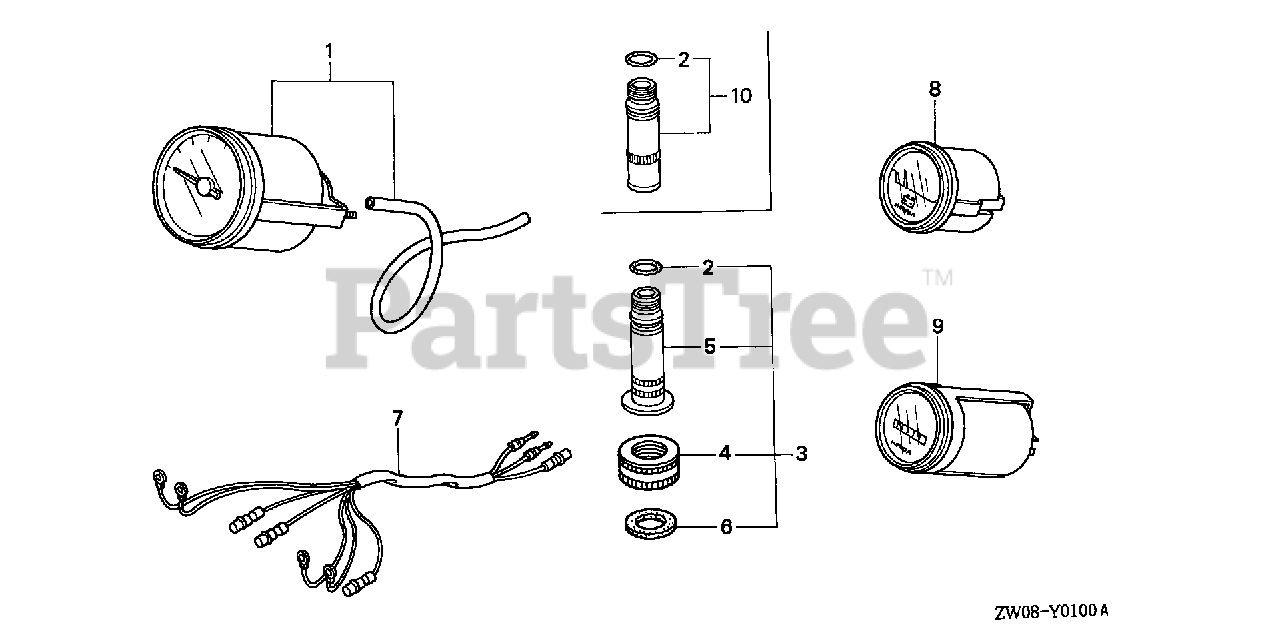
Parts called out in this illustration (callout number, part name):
1	SPEEDOMETER KIT
2	O-RING (11.8X2.4)
3	JOINT ASSY., HOSE
4	NUT, WATER MOUTH Use from Frame SN 1000929.
5	JOINT ASSY., HOSE
6	SEAT, WATER MOUTH Use from Frame SN 1000929.
7	HARNESS ASSY., METER (B)
8	METER ASSY., VOLT (NOT AVAILABLE: USE 37453-ZW5-000ZA)
9	METER ASSY., HOUR L.C.D.
